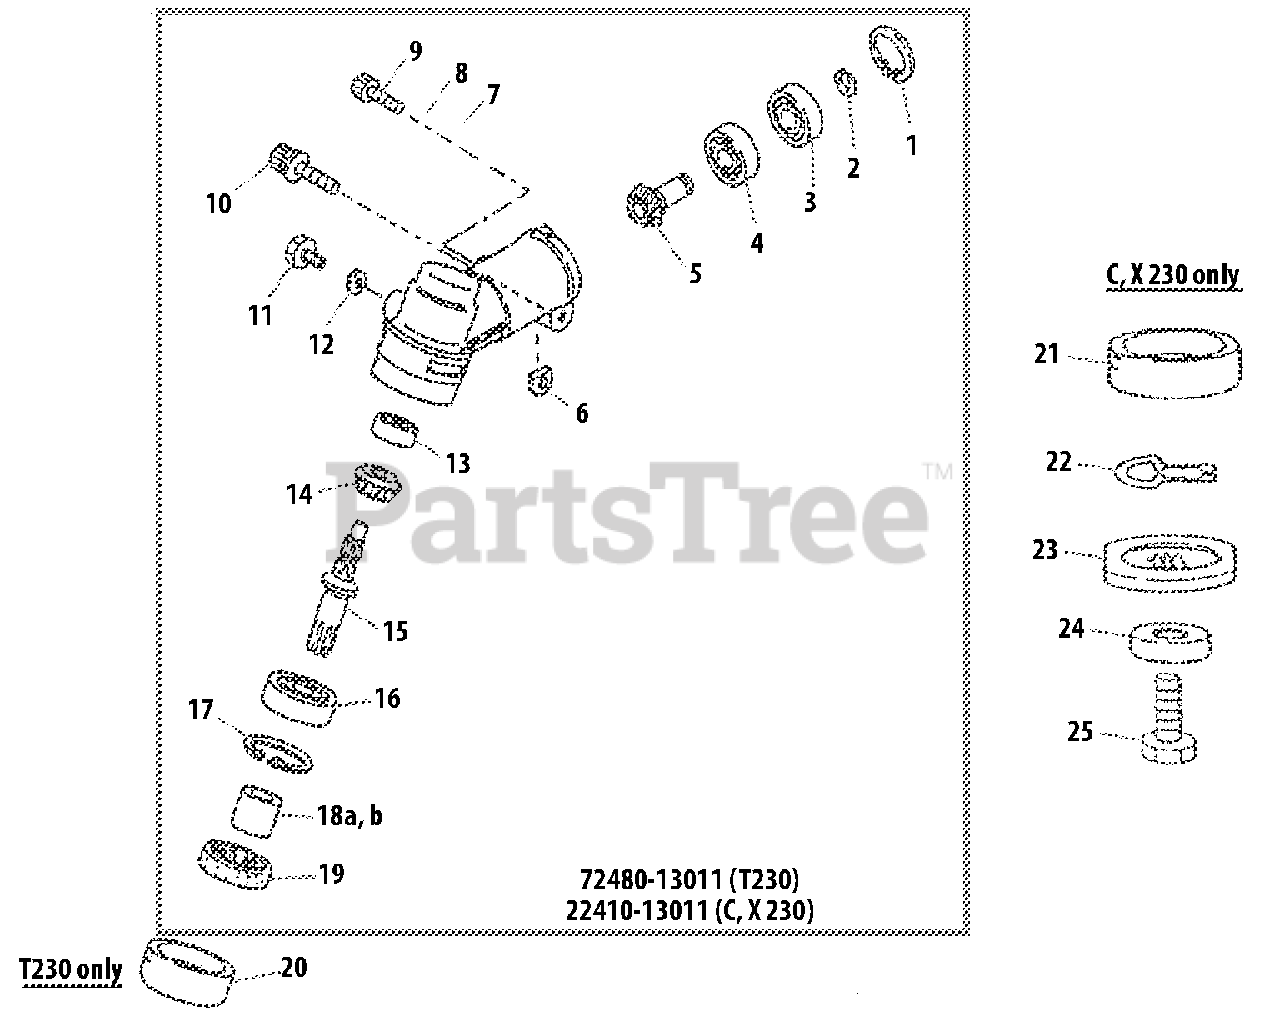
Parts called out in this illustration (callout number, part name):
1	RING, RETAINING - 22
2	RING, RETAINING
3	BEARING, BALL - 608ZZ
4	BEARING, BALL - 608
5	GEAR - SHAFT
6	SHIM
7	WASHER - 5
8	LOCKWASHER - 5
9	SCREW - 5X12
10	SCREW - 5X25
11	BOLT - 6X10
12	WASHER
13	BEARING, BALL - 626
14	GEAR - BEVEL
15	GEAR - SHAFT
16	BEARING, BALL - 6000
17	RING, RETAINING - 26
18	COLLAR
19	SEAL, OIL
20	HOLDER
21	HOLDER - A
22	SLIDE CLIP
23	HOLDER B, REPLACES 22035-13251, REPLACES 22553-13250
24	GUARD
25	BOLT - 7X18 -- LEFT HAND
22410-13011	GEAR CASE ASSY
72480-13011	GEAR CASE ASSY
